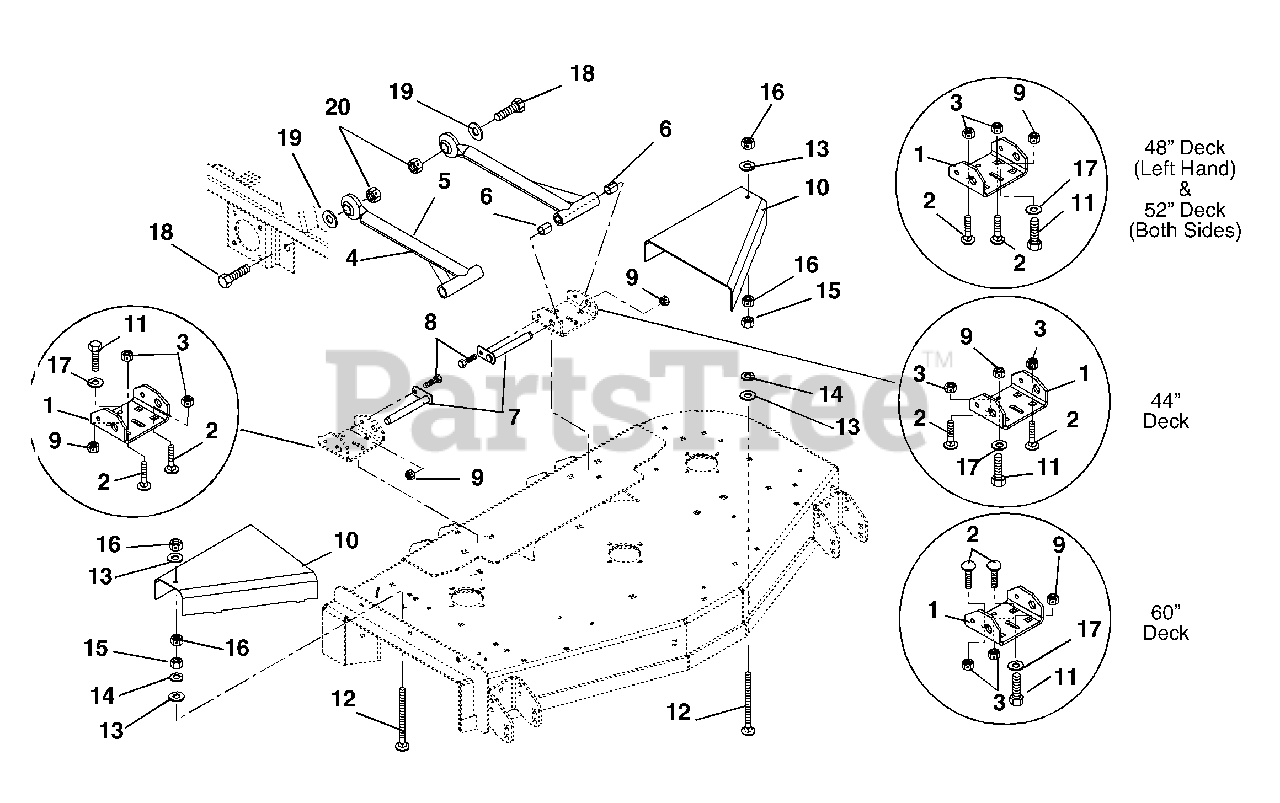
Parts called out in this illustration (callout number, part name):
1	Bracket, Mower Mounting (Rear)
2	Bolt, Round Head Square Neck .50-13 x .75 Grade 5
3	Nut, Locking Center Jam .50-13
4	Assembly, Mower Mounting
5	Mower Mounting Arm
6	Bearing, .75 x .875 x 1.00
7	Weldment, Mower Mounting Pin
8	Bolt, Hex .38-16 x .75 Grade 5
9	Nut, Locking Top Flange .38-16
10	Guard, Pulley Left Hand (079, 081)
10	Guard, Pulley Right Hand (079, 081)
10	Guard, Pulley Left Hand (080, 082)
10	Guard, Pulley Right Hand (080, 082)
10	Guard, Pulley (077, 078)
11	Bolt, Round Head Square Neck .38-16 x .75 Grade 5
12	Bolt, Round Head Square Neck Full Thread .312-18 x 3.50 (077, 078, 079, 081, 310, 311)
12	Bolt, Round Head Square Neck Full Thread .312-18 x 3.50 (080, 082)
13	Washer, Flat Steel .344 x .688 x .065 (077, 078, 079, 081, 310, 311)
13	Washer, Flat Steel .344 x .688 x .065 (080, 082)
14	Washer, Locking .31 x .078 (077, 078, 079, 081, 310, 311)
14	Washer, Locking .31 x .078 (080, 082)
15	Nut, Hex .31-18 (077, 078, 079, 081, 310, 311)
15	Nut, Hex .31-18 (080, 082)
16	Nut, Locking Center .31-18 (077, 078, 079, 081, 310, 311)
16	Nut, Locking Center .31-18 (080, 082)
17	Washer, Flat Steel .406 x .812 x .065
18	Bolt, Hex .875-9 x 2.75 Grade 5
19	Washer, Flat Steel .875 x 1.50 x .120
20	Nut, Locking Center .875-9
